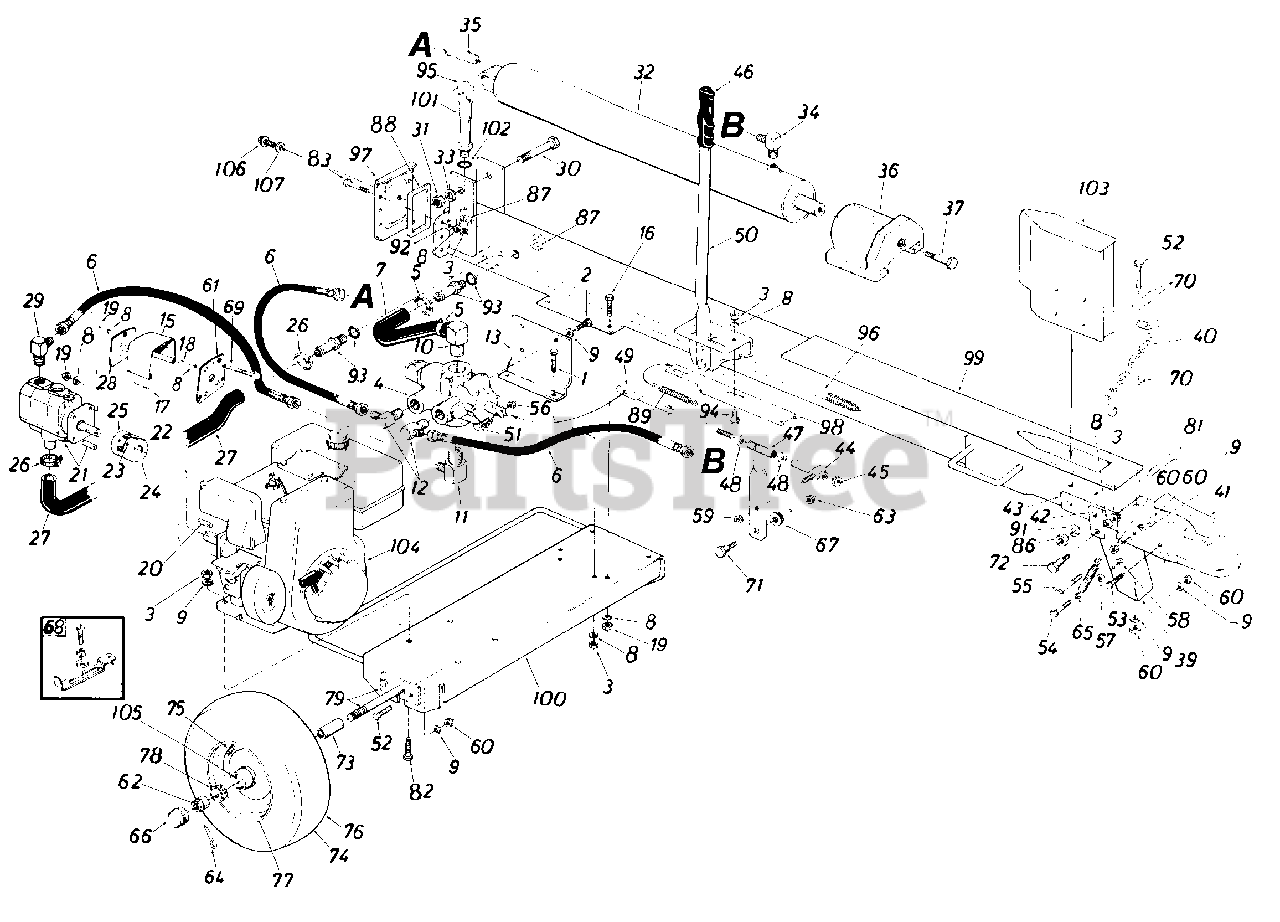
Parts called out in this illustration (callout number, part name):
1	Hex Bolt 5/16-18 x .75 " Lg.
2	Hex Bolt 3/8-16 x .50" Lg.
3	Hex Nut 5/16-18 Thd.
4	Control Valve 400
5	Hose Clamp 5/8"
6	High Pressure Hose Ass'y. .38" I.D.
7	Return Hose-Valve to Tank 3/4" I.D.
8	L.-Wash. 5/16" I.D.
9	L.-Wash. 3/8" I.D.
10	Return Elbow
11	90ø Solid Male Adapter
12	90ø Solld Male Adapter
13	Valve Mtg. Plate
15	Coupling Shield
16	Hex Bolt5/16-24x 1.00" Lg.
17	Hex Bolt 5/16-24 x .75" Lg.
18	Hex Bolt 5/16-24 x .62" Lg.
19	Hex Nut 5/16-24 Thd.
20	Sq. Key 3/16" x 2.25" Lg.
21	Pump with Woodruff Key
22	Spider L-0-90
23	Set Scr. 1/4-20 x .25" Cup
24	Coupling Half .75" I.D.
25	Coupling Half .50" I.D.
26	Hose Clamp 5/8"
27	Suction Hose 1.0" Dia.
29	90ø Solid Male Adapter
30	Hex Bolt 3/4" x 4.0" Lg.
31	Hex Nut 3/4" Thd.
32	Hydraulic Cylinder 3-1/2" Dia.
33	L.-Wash. 314" I.D.
34	High Pressure 90ø Elbow
35	45ø Male Adapter 3/4-16 MJ-3/8-18 NP
36	Pusher Plate
37	Shoulder Bolt .62" Dia. x 4.75 " Lg.
39	Flip Stand Bracket
40	Chain-Tovl/ Hitch
41	Tow Hitch Ass'y. Comp.
42	Stand Pivot Bracket
43	Tow Hitch Brk't. 2 x 3/16 10.25" Lg.
44	Ferrule Ass y.
45	Hex Cent. L.-Nut 3/8-24 Thd.
46	Grip-Black Vinyl
47	Comptession Spring
48	Special Washer .378 x 1.00" x .125 Thd.
49	Engagement Rod 3/8" Dia. x 9.0' Lg.
50	Engagement Handle
51	Hex Bolt 1/4-20 x 1.75" Lg.
52	Hex BoIt 3/8-24 x 1.25" Lg.
53	Hex Bolt 3/8-24 x .75" Lg.
54	Hex Bolt 1/4-28 x 1.00" Lg.
55	Hex Bolt 3/8-24 x 1.75" Lg. (Grade 5)
56	Hex Patch L.-Nut 1/4-20 Lg.
57	Hex Cent. L.-Nut 1/4-28 Thd.
58	Hex Nut 1/4-28 Thd.
59	Hex Cent. L.-Nut 5/16-18 Thd.
60	Hex Nut 3/8-24 Thd.
62	Hex Castle Nut 3/4-16 Thd.
63	Hex L.-Nut 3/8-16 Thd.
64	Cotter Pin 5/32" Dia. x 1.25" Lg.
65	Extension Spring .50" O.D. 3.97 " Lg.
66	Hub Cap
67	Rubber Washer
68	Throttle Control
69	Hex Bolt 5/16-24 x 4.0" Lg.*
70	Fl.-Wash. .375" I.D. x .870" O.D. x .090
71	Shoulder Bolt .498" Dia. x .340" Lg.
72	Shoulder Bolt .437" Dia. x .268" Lg.
73	Spacer .75" I.D. x 1.12" O.D. x 1.56" Lg.
75	Air Valve-Tubeless
76	Tire Only 16.0 x 4.0-2 Ply
78	Roller Rearing 3/4" I.D.
79	Axle Ass'y. .75" Dia. x 36.25 " Lg.
81	Hex Bolt 5/8-18 x 3.50" Lg.
82	Hex Bolt 5/16-24 x 1.75" Lg.
83	Hex BoIt 5/16-18 x 1.50" Lg.
86	Hex Nut 5/1-18 Thd.
87	Hex Nut 11/16-12 Thd.
88	Gasket 2.62 x 5.12
89	ExtensiGn Spring .50" O.D. x 4.25" Lg.
91	L.-Wash. 5/8" I.D.
92	Fl.-Wash. 34" I.D. x .68" O.D. x .062 Thk.
93	IAdapter 1.0" Tube 11/16-12 "O"-Ring
94	IShoulder Bolt .437" Dia. x .180" Lg.
95	Breather Cap
96	Strainer Tube Ass'y.
97	End Plate
98	Engagement Brk't. 1.39 x 11.75" Lg.
99	Complete Oil Tank Ass'y.
100	Engine Frame Ass'y.
101	Filler Tube Ass'y.
102	"O"-Ring92" I.D. x 1.16" O.D. x .116 Dia.
103	Wedge Ass'y.
104	5 H.P. Engine
105	Bearing Seal
106	Hex Hd. Tap Scr. 5/16"
107	Gasket
